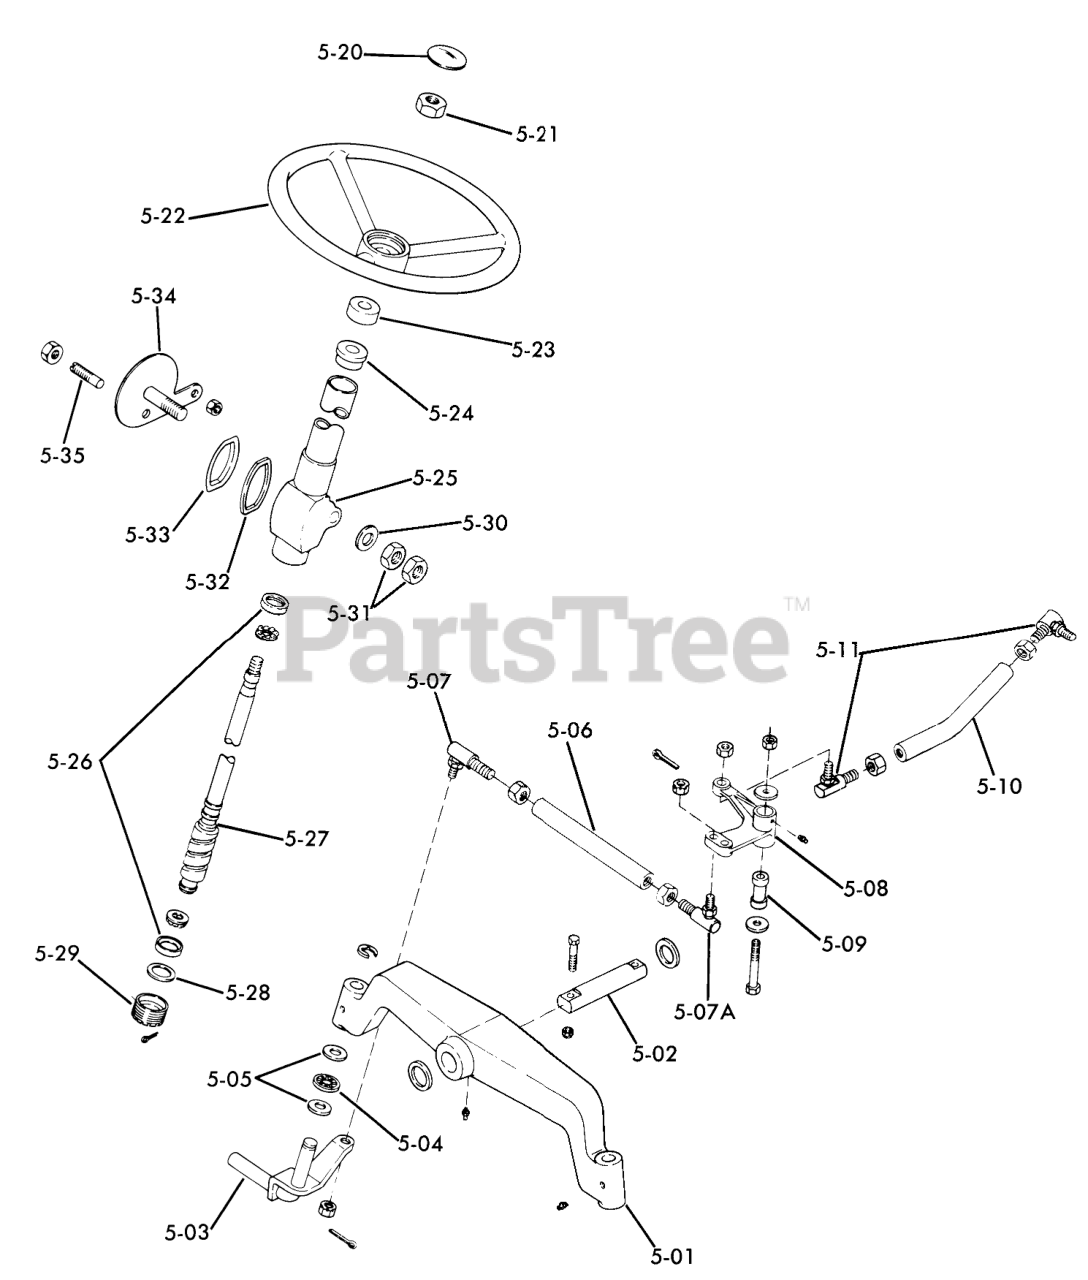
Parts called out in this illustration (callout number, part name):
5-01	Axle Front
5-02	PIN AXLE
5-03	Spindle Assembly R.H.
5-04	BEARING-THRUST
5-05	WASHER-THRUST
5-06	TIE ROD R
5-07	Ball Joint RH
5-07A	LH BALL JOINT R
5-08	Bellcrank-steering
5-09	Bushing
5-10	Drag Link
5-11	BALL JOINT-SHORT R
5-20	STEERING WHEEL INSE
5-21	Nut
5-22	Steering Wheel
5-23	Cover-Dust
5-24	Column Bearing
5-25	Assy-Housing and Column
5-26	BALL CUP KIT
5-27	Steering Gear
5-28	WASHER
5-29	Adjusting Plug
5-30	Washer 49/64 X 1 1/4
5-31	Nut
5-33	Retainer-Seal
5-34	Lever
5-35	Stud
